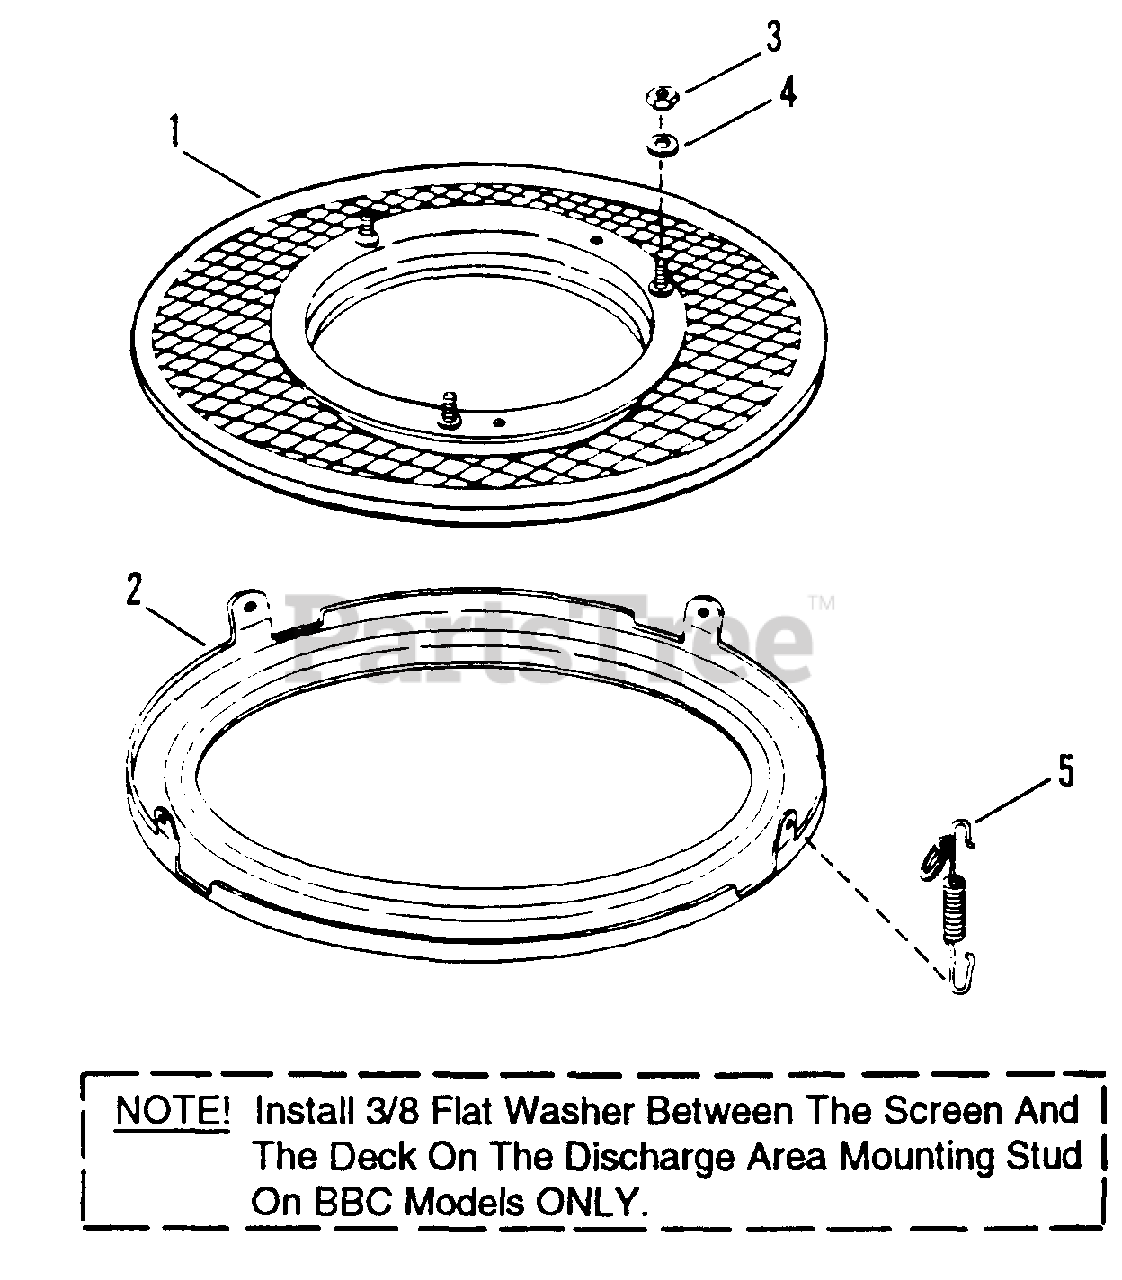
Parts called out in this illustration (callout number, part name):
1	SCREEN, Fastener Assembly
2	RING, Bottom
3	NUT, 5/16-24 Hex
4	WASHER, 5/16 Split Lock
5	SPRING
